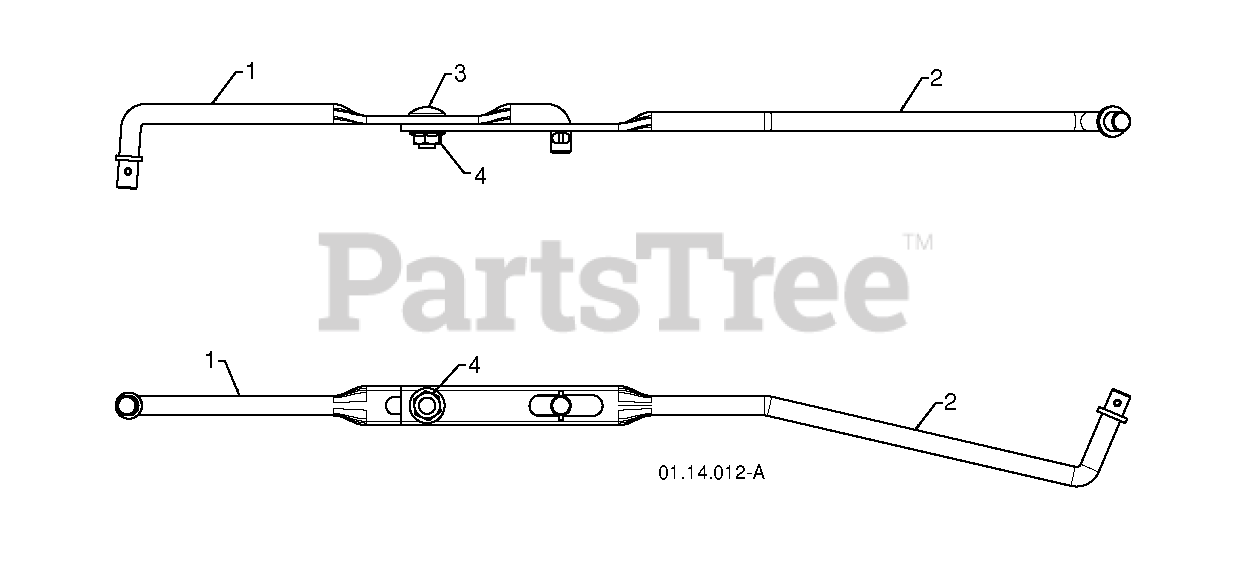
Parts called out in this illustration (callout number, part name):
1	ROD, UPPER SPEED CONTROL
2	ROD, LOWER SPEED CONTROL
3	BOLT
4	NUT.FLANGE.5/16
